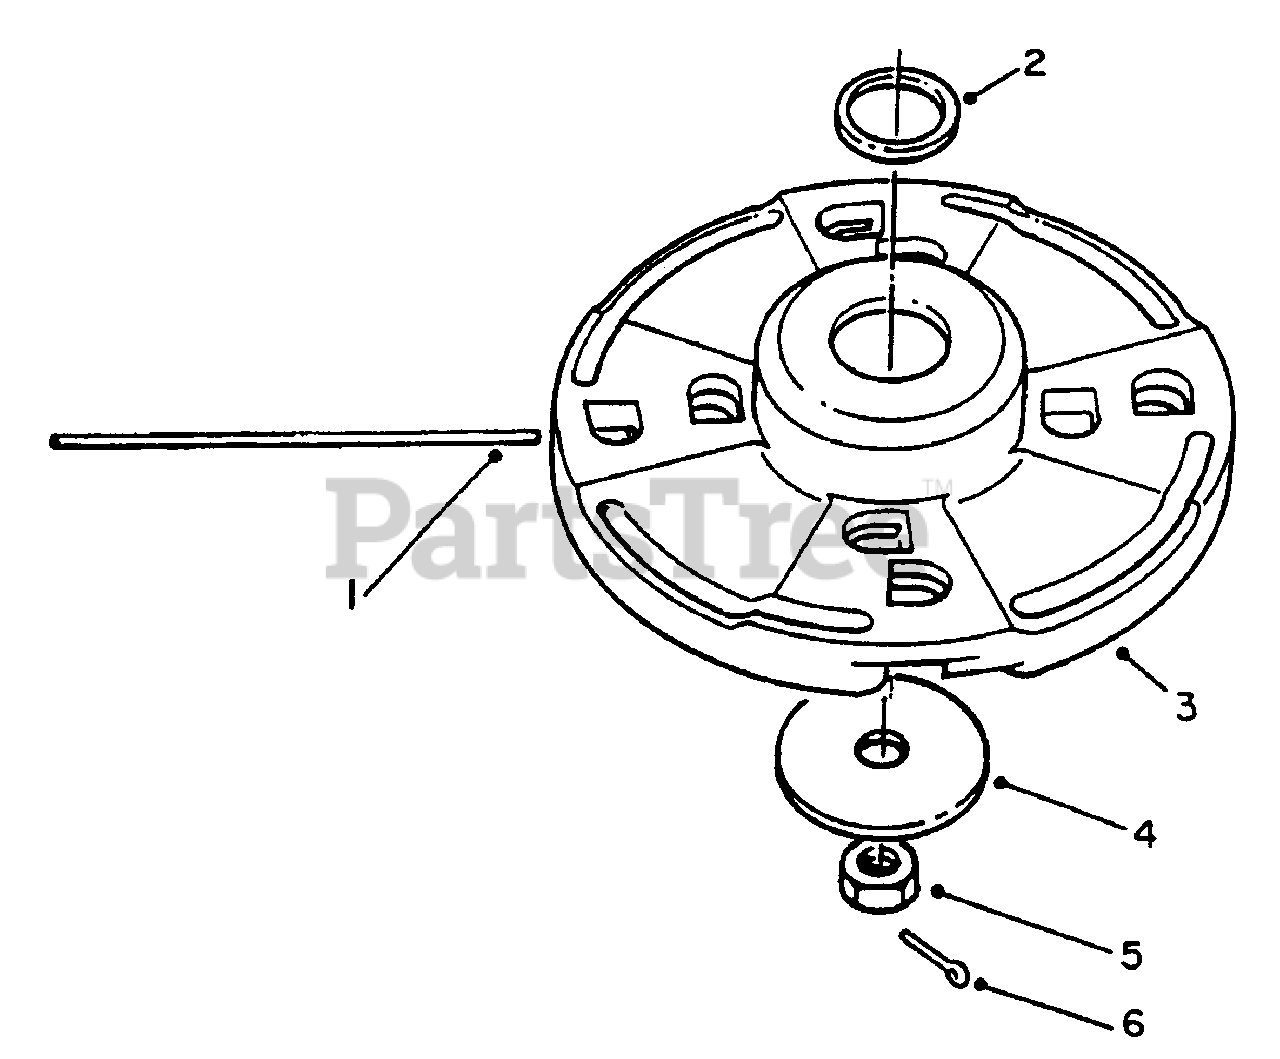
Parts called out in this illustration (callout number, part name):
1	Line-Cutting
3	Head Assembly (Incl.Ref. #2)
4	Washer-Plate
5	Nut-L.H.
6	Pin-Cotter
